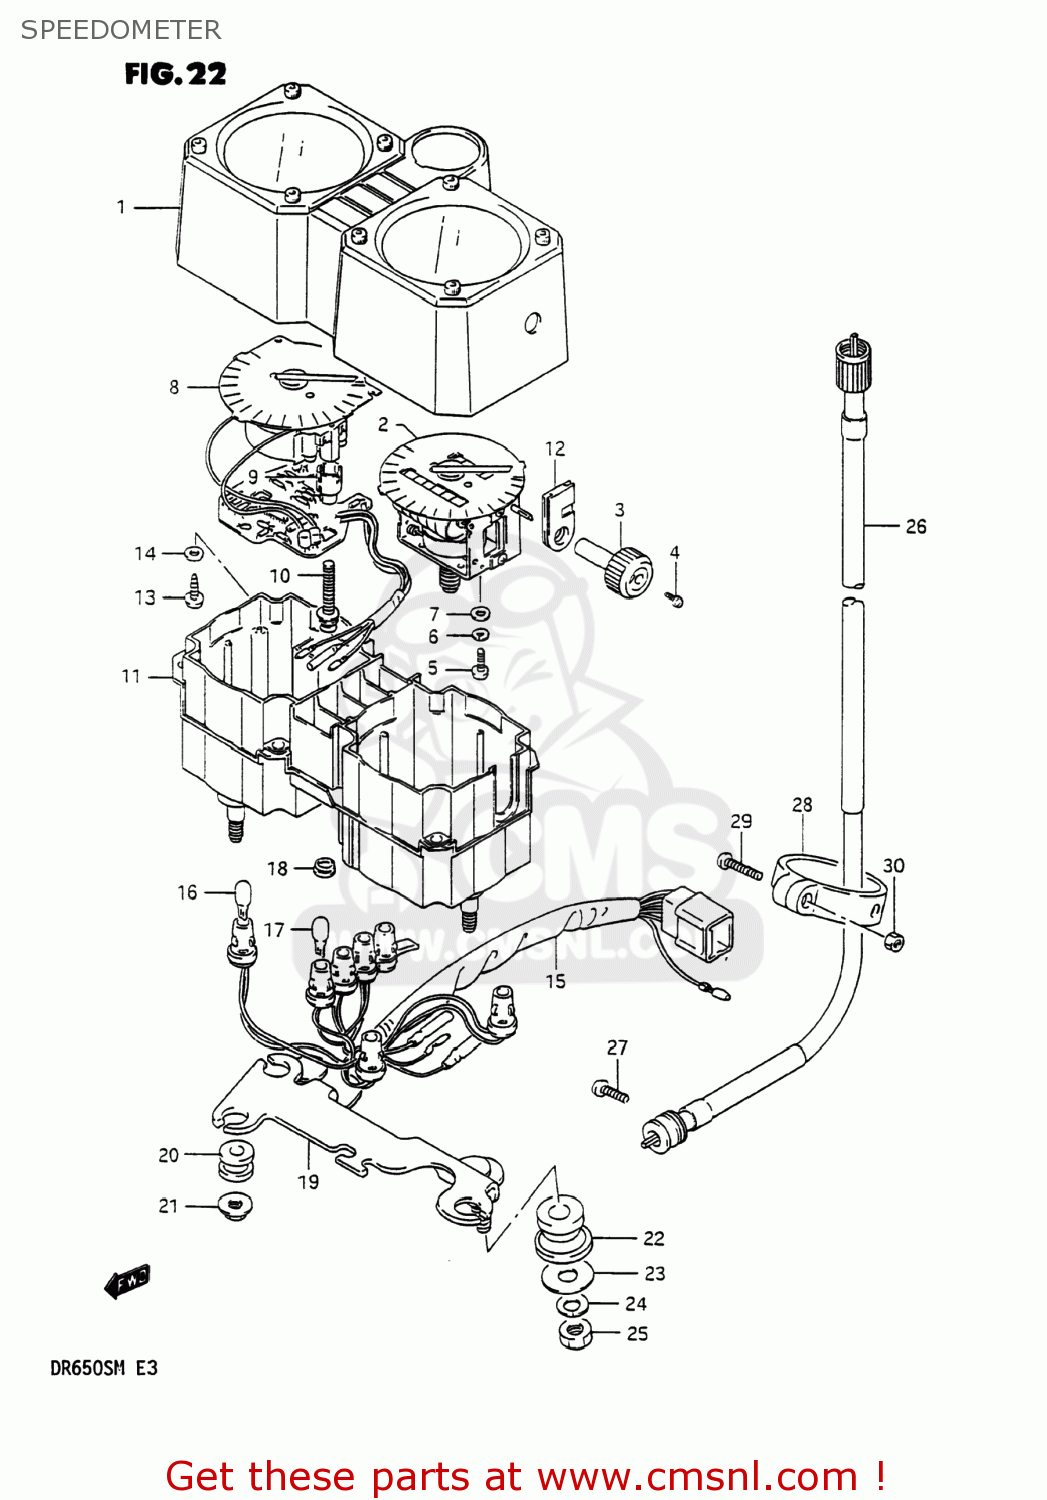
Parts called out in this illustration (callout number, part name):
1	HOOD,METER
2	SPEEDOMETER
3	KNOB,TRIP
4	SCREW,TRIP KNOB
5	SCREW
6	LOCK WASHER
7	WASHER 3.3X8X0
8	TACHOMETER
9	SPACER
10	SCREW
11	CASE,METER
12	CUSHION,METER
13	SCREW
14	LOCK WASHER
15	SOCKET,METER
16	BULB(12V1.7W,WB372,T7)
17	BULB(12V3W,WB371,T7)
18	CAP
19	BRACKET,METER
20	CUSHION,METER
21	NUT
22	CUSHION,METER BRACKET
23	WASHER (8.5X20X1.6)
24	WASHER,LOCK,8.
25	NUT ,8MM
26	CABLE ASSEMBLY,SPEEDOMETER
27	SCREW
28	CLAMP,SPEEDOMETER CABLE
29	SCREW
30	NUT
